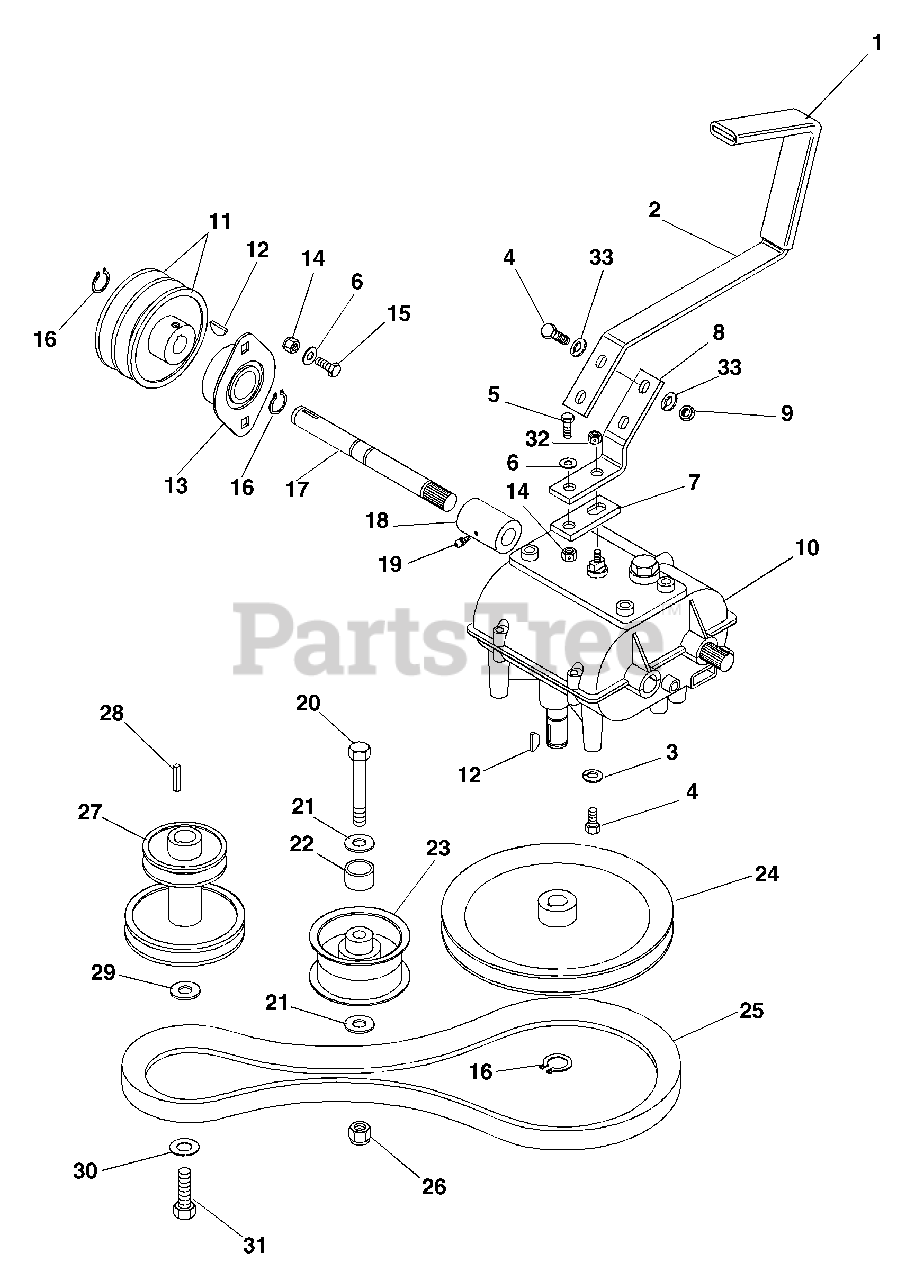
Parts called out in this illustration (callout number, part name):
1	GRIP - HANDLEBAR
2	LVR,TRANS SHIFT
3	@WSHR-LK .31X.078 REG YWZC
4	@BLT-HEX .31-18X1.00 GR5 YWZC
5	@BLT-HEX .25-20X1.00 GR5 YWZC
6	@WSHR-FL-STL.281X.62X.065 YWZC
7	PLATE, SHIFT
8	ARM, SHIFT
9	@NUT-LK-CTR .31-18 YWZC
10	TRANSMISSION
11	KIT-DRIVE SHEAVE
12	KEY-WDRF .19X.75 HRD #9
13	BRG-FLG .625X1.875X.797
14	@NUT-LK-CTR .25-20 YWZC
15	@BLT-HEX .25-20X.75 GR5 YWZC
16	RG-RTNG-EXT .579X.035
17	SHAFT, HALF
19	FTG,LUBE, .25-28 SELF THREAD
20	@BLT-HEX .38-16X2.25 GR5 YWZC
21	@WSHR-FL-STL.406X.812X.065 YWZ
22	SPACER .625X.385X.55
23	IDLER-PLY FLAT 3.25 X .38 X1.0
24	PLY-V 7.50X.626
25	V-BELT, HA-RAW EDGE
26	@NUT-LK-CTR .38-16 YWZC
27	CRANK SHEAVE-PRO
28	KEY-SQ .248X2.38
29	WSHR-LK .44X.109 REG YWZC
30	WSHR-FL-STL .469X2.00X.25 YWZC
31	BLT-HEX M10 X 1.5X60 8.8 YWZC
32	NUT-LK-CTR .375-24 YWZC
33	@WSHR-FL-STL.344X.688X.065YWZC
